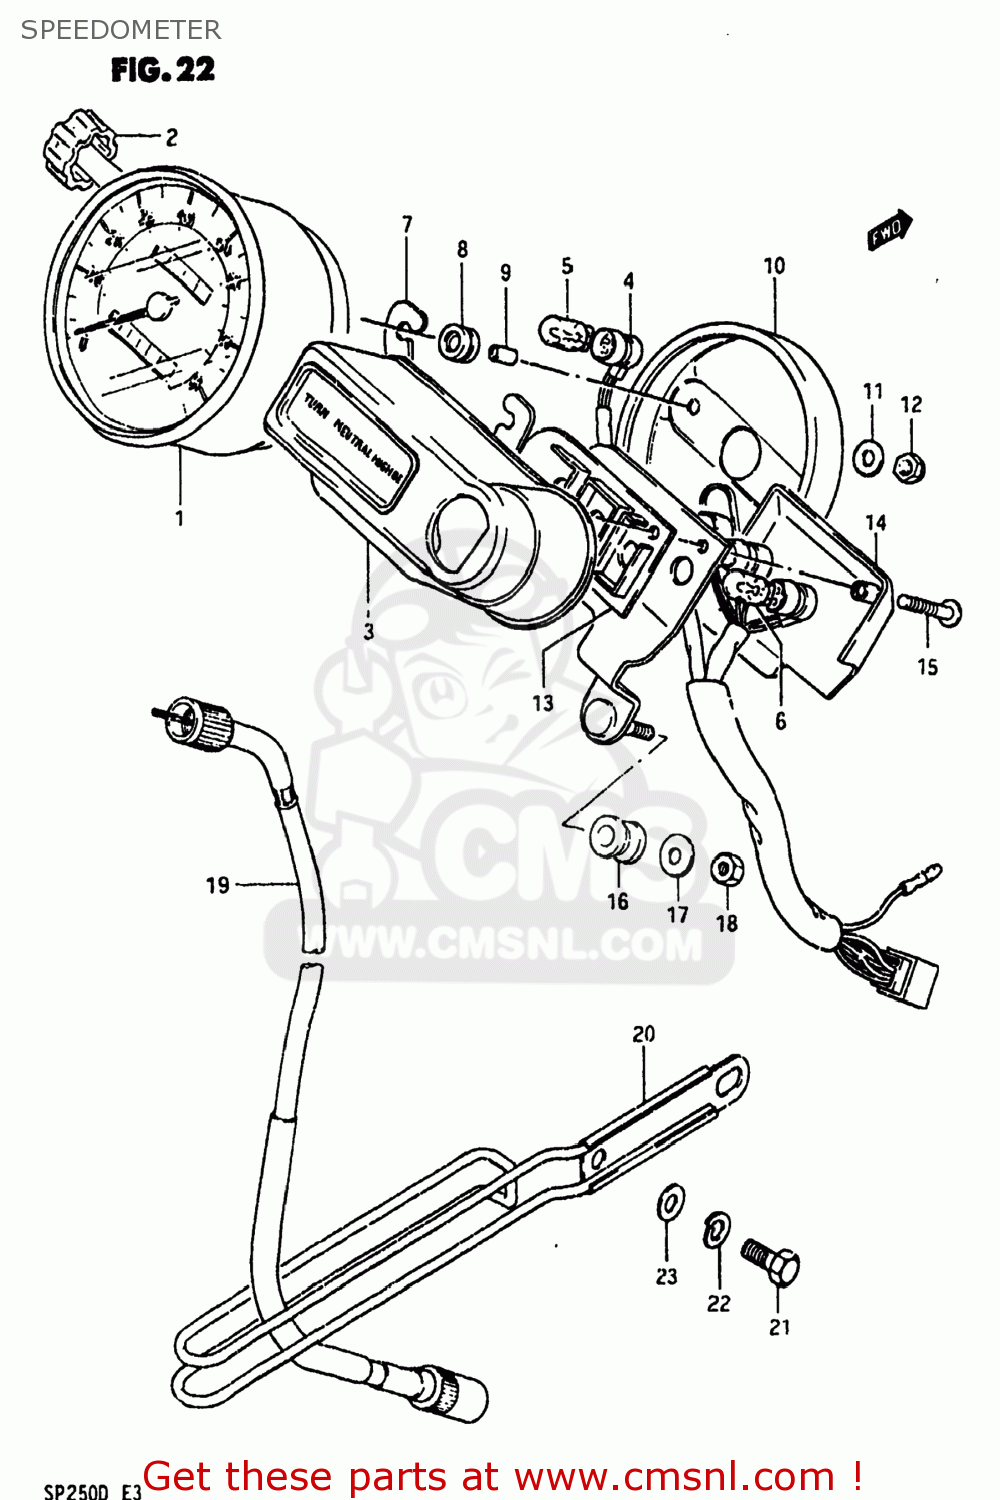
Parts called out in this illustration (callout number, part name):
1	SPEEDOMETER ASSEMBLY
2	KNOB,TRIP
3	CASE,PILOT BULB
4	SOCKET,METER
5	BULB(6V,3W)
6	BULB(6V1.7W,STANLEY,A61A)
7	BRACKET,METER
8	CUSHION,METER
9	SPACER,METER
10	BRACKET,SPEEDOMETER,UNDER
11	WASHER,METER
12	NUT
13	HOLDER,SOCKET
14	COVER,PILOT BOX
15	SCREW
16	CUSHION
17	WASHER
18	NUT
19	CABLE ASSEMBLY,SPEEDOMETER
20	GUIDE,CABLE
21	BOLT 8X12
22	LOCK WASHER
23	WASHER
